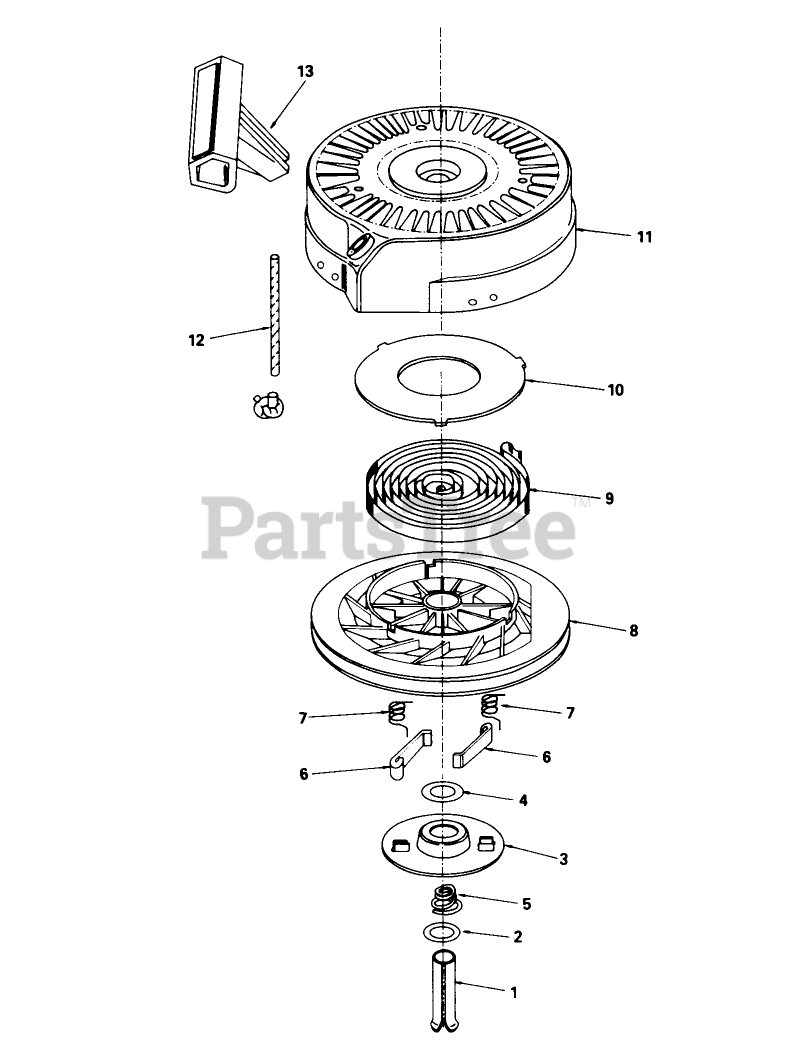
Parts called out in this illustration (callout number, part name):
1	Pin-Spring (Incl. Ref. #4)
3	Retainer
5	Brake Spring
6	Dog-Starter
7	Spring-Dog
8	Pulley
9	Rewind Spring
10	Cover-Spring
11	Housing-Starter
12	Rope-Starter (98 cut to length)
13	Handle-Starter
